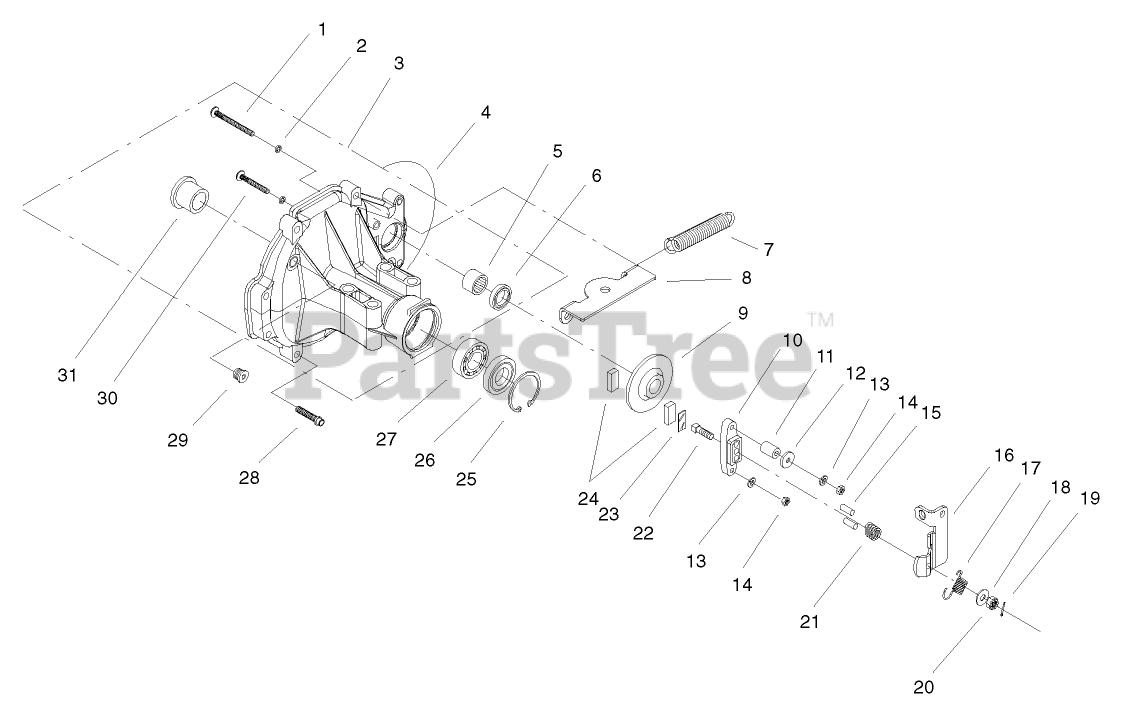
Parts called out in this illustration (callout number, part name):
2	O-RING
3	RH HOUSING ASM
4	SEALANT
5	BEARING-NEEDLE
6	SEAL-LIP
7	SPRING-RETURN
8	BRACKET-CRANK, BELL
9	DISK-BRAKE
10	YOKE-BRAKE
11	SPACER
12	WASHER
13	WASHER-LOCK
15	PIN-BRAKE
16	ARM-BRAKE
17	SPRING-ARM, BRAKE (BIAS)
20	NUT-CASTLE
21	SPRING-BRAKE, ANTI DRAG
22	BOLT-SQH
23	PUCK-PLATE
24	PUCK-BRAKE
25	RING-RETAINING
27	BEARING-BALL
28	SCREW-TTH
29	PLUG-THREAD, STRAIGHT
31	BEARING-FLANGE
